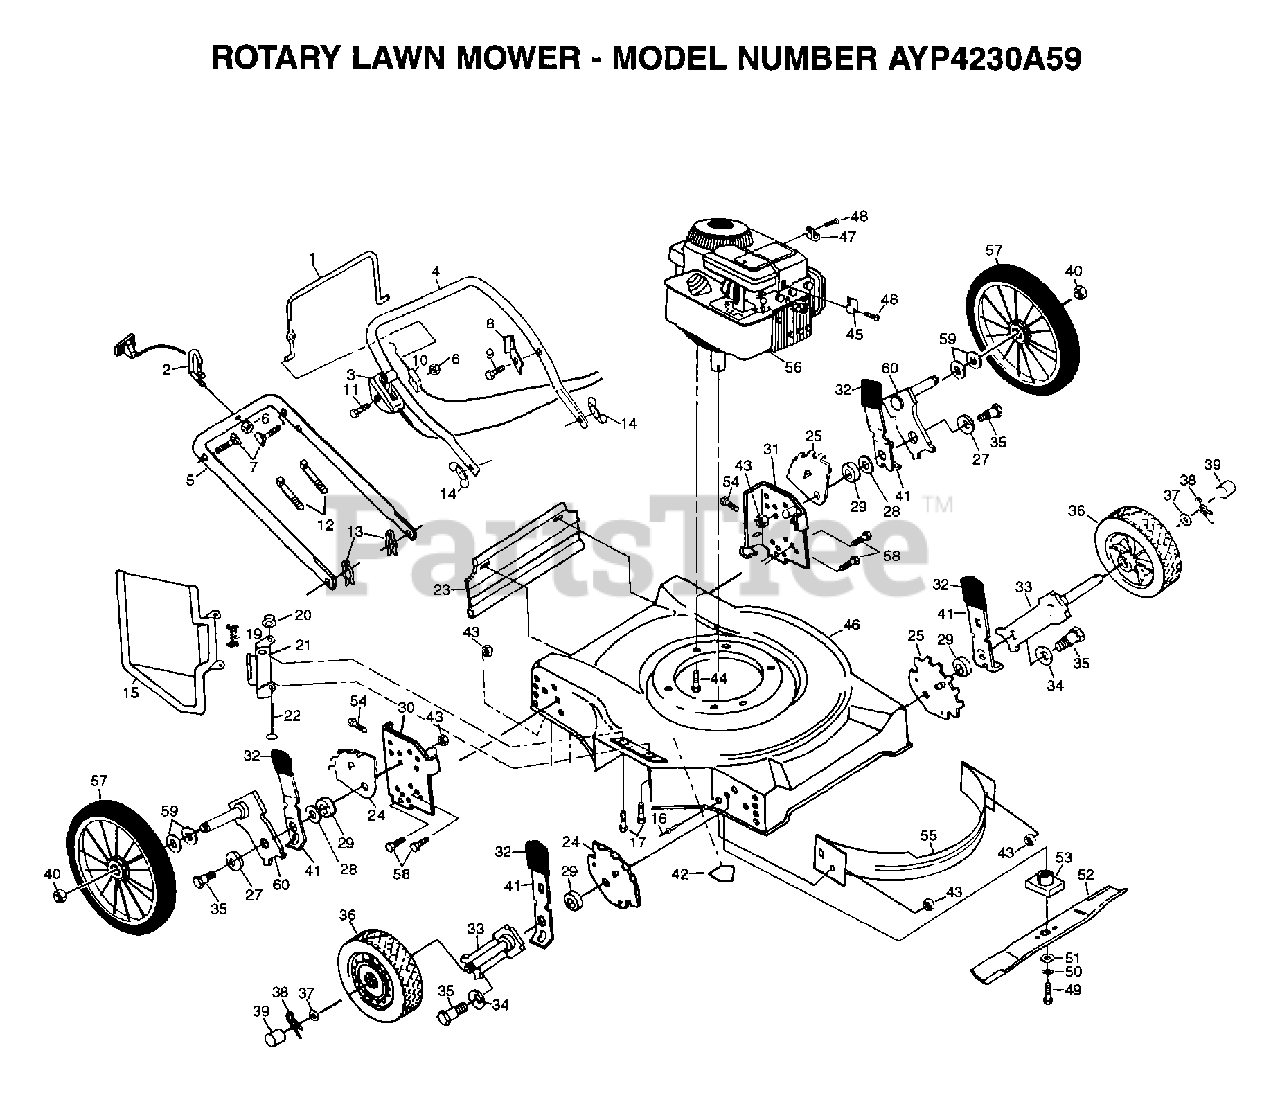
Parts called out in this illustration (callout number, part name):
1	CONTROL BAR PM
2	ROPER GUIDE PM
5	HANDLE.LOWER.ECON
7	BOLT.HANDLE.LM
8	"BRKT,UPSTOP"
9	TAPPING SCREW
10	CABLE.CONT.ENG
11	SCREW.HXHD.WASH.
13	HAIRPIN COTTER
14	"NUT,WING PM"
15	"GRD,DISCHARGE"
16	BLIND RIVET
17	SCREW
19	"SPRING,TORSION"
20	PUSH ON SPEED NUT
21	"BRKT,HSG "
23	SKIRT.RD.20/22
24	BRACKET.WHL.ADJ.L
25	BRACKET.WHL.ADJ.R
28	WASHER PM
30	BRACKET.SUPT.HDLE
31	BRACKET.SUPT.HDLE
32	KNOB PM
33	AXLE ARM
34	"WASHER, BELLEVIL."
35	BOLT SHLD 3/8-16
36	WHEEL ASSY
37	WASHER
38	RETAINER CLIP PM
39	HUB CAP-PLASTIC
40	HEX FLANGE LOCKNT
41	SPRING SELECTOR
42	DECAL-DANGER PM
43	LOCKNUT PM
44	SCREW
45	CABLE CLAMP
46	KIT.HSG.20SD.PUSH
47	GUIDE CLIP PM
48	SCREW PM
49	SCREW
50	LOCKWASHER
51	"WASHER,HARDEN"
52	BLADE.STAND.20INC
53	BLADE ADAPTOR
54	SCREW
59	WAVE WASHER
60	"AXLE ARM,REAR PM"
